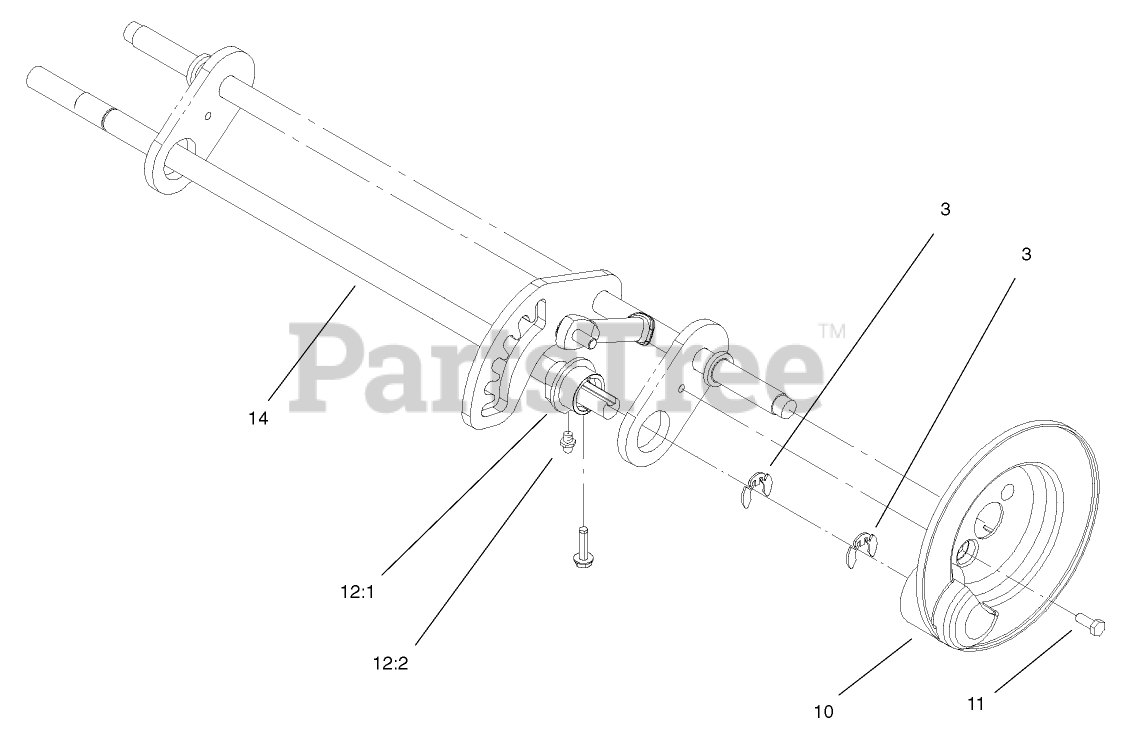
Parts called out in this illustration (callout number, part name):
3	RING-RETAINING,CLIP
10	COVER-GEAR
11	SCREW-TAPTITE
12	BUSHING ASM
12:2	FITTING-GREASE
14	SHAFT-PIVOT
